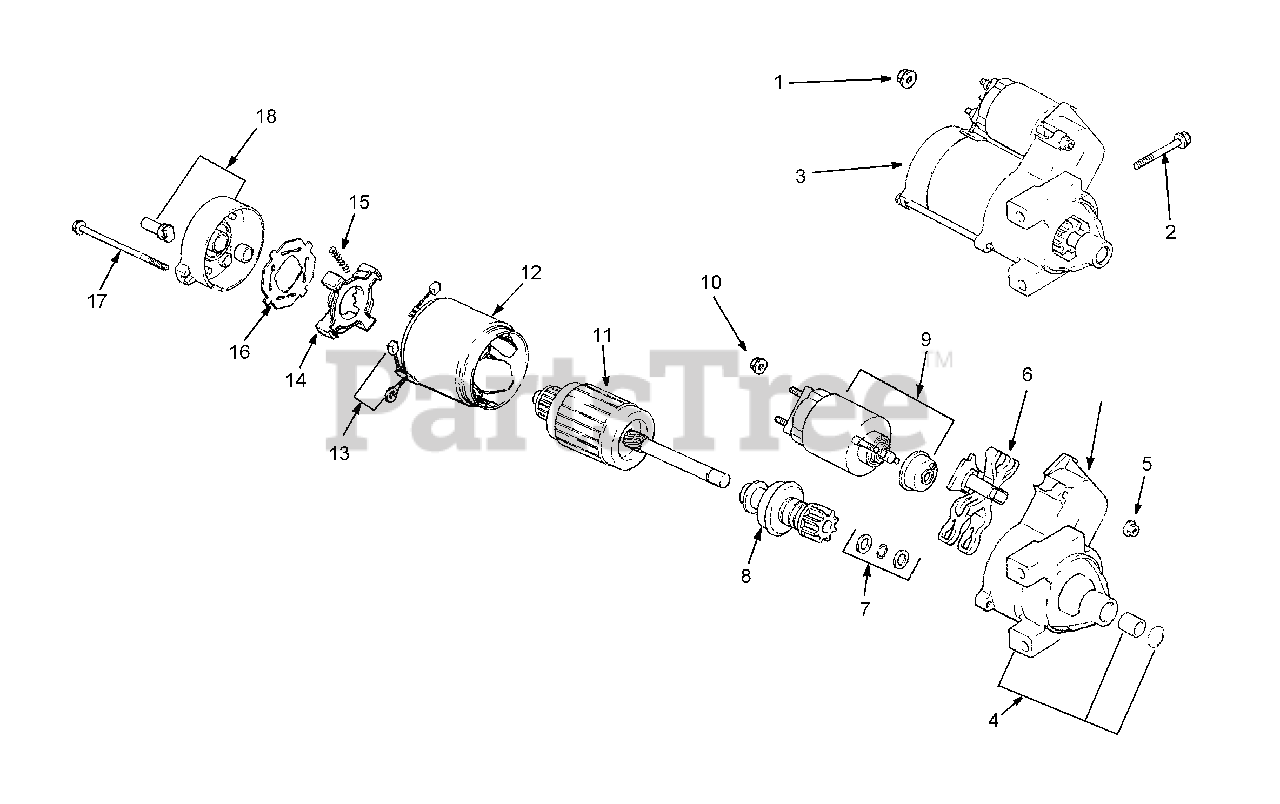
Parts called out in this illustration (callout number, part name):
1	Nut, Hex Flange M8 x 1.25"
2	Screw, Hex Flange M8 x 1.25 x 80
3	Starter, Solenoid Shift Assembly
4	Drive, End Cap
5	Nut, Starter
6	Lever, Starter Drive
7	Kit, Starter repair
8	Drive, Pinion
10	Nut, Starter
11	Armature, Starter
13	Kit, Brush & Spring
14	Holder, Brush
15	Spring, Brush
18	Commutator, End Cap
